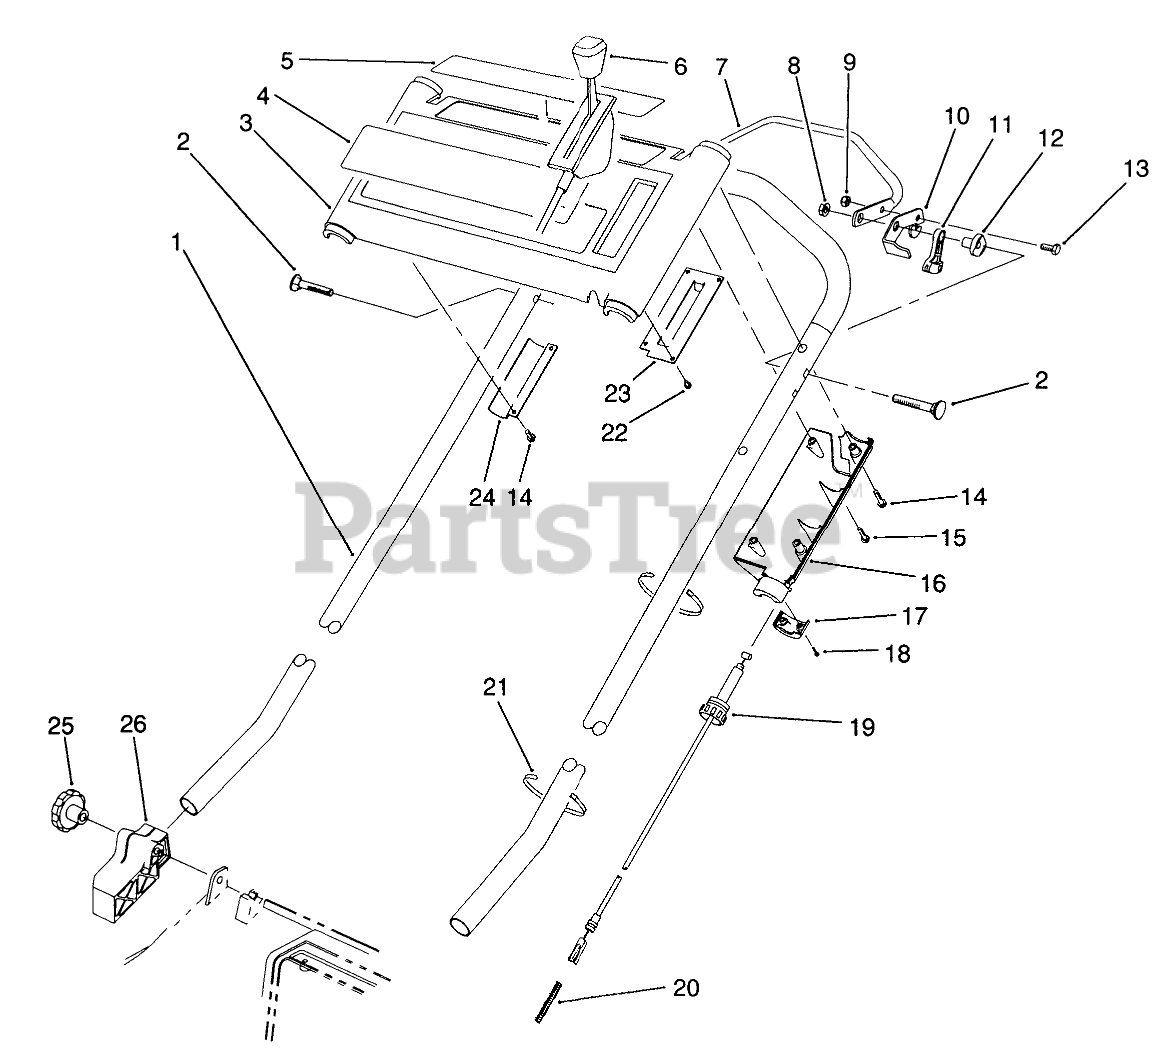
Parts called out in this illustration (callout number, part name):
1	Handle
2	SCREW-HANDLE
3	Panel-Control (Incl. Ref. #4 & 5)
4	DECAL - TORO
5	DECAL - PANEL DANGER
6	Control-Throttle Bend Type #1 Sheath Lg. 55.50 Wire Lg. 2 1/2
7	CONTROL BAR
8	NUT-LOCK, NI
9	NUT-LOCK, NI
10	CONTROL LEVER
11	LEVER-TRACTION
12	SPACER-SUPPORT
13	SCREW-HH
14	SCREW-PPH, PLASTITE
15	Screw
16	Cover-Throttle Lower
17	LOWER THROTTLE CAP
18	#4-14X.62 PLASTITE SCW
19	TRACTION CABLE
20	SPRING-COMPRESSION
21	TIE-CABLE
22	#6-19X.25 PLASK FORM SC
23	THROTTLE PLATE
24	Bracket-Panel
26	MOUNT-HANDLE, RH
